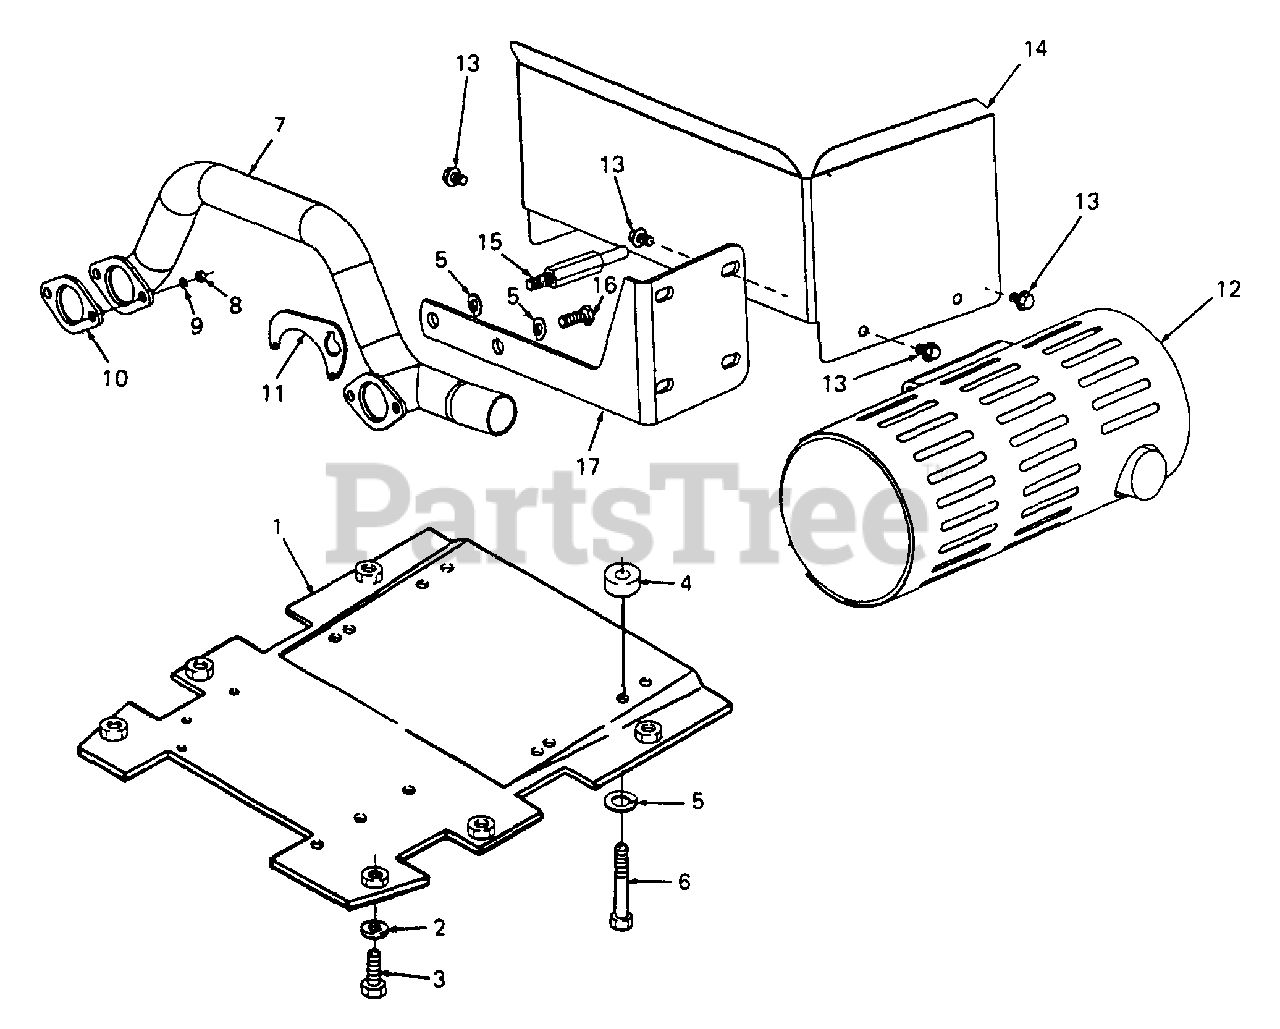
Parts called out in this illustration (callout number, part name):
3	Bolt, Patch, 3/8-16 x 1.0 Lg
4	Spacer, .35 ID x 1.0 OD x .80 Lg
5	Washer, Lock, 5/16
6	Screw, Hex Cap, M8 x 1.25 x 40 MM Lg
7	Pipe, Exhaust
8	Nut, Hex, 6 MM
9	Washer, Lock
10	Gasket, Exhaust
11	Bracket, Lift
13	Screw, Hex Wash Hd, Tapp, 1/4-20 x .375 Lg
14	Shield, Battery Heat
15	Stud, Clutch Stop
16	Screw, Hex Cap, M8 x 1.25 x 20 MM GR5
17	Bracket, Muffler Mtg
